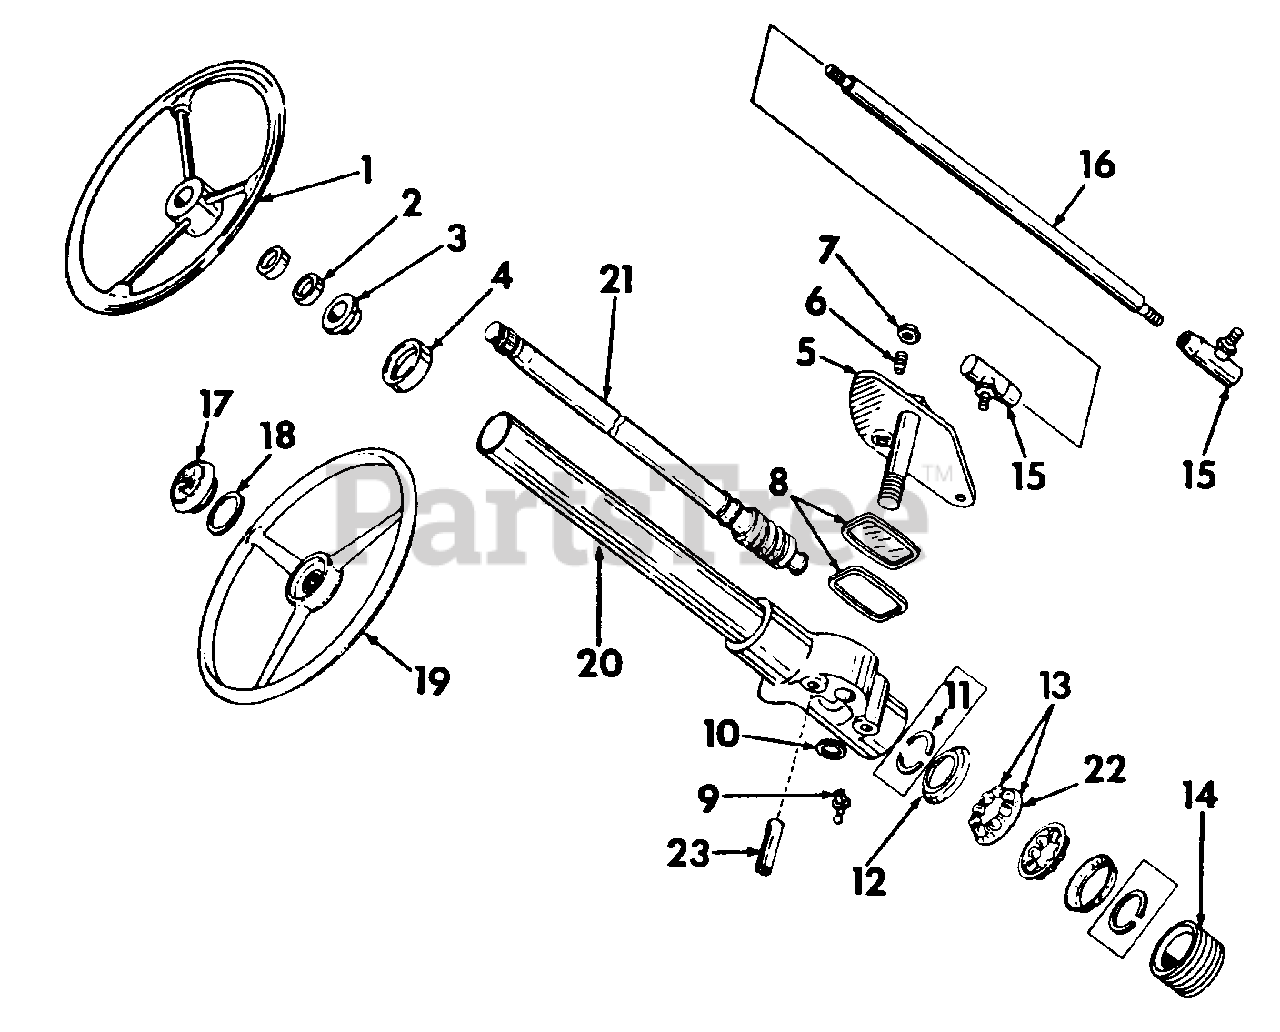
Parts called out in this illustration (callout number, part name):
2	Seal, Steering Gear
3	Bearing, Column Upper
4	Retainer, Bearing
5	Lever & Bolt Assy
6	Stud, Cam Follower
7	Nut, Cam Follower Stud
8	Package, Seal & Seal Retainer
9	Fitting, 1/4 65 Deg Angle Drive Lube
10	Washer, Flat, Bronze
12	Retainer, Bearing Ball
13	Retainer & Ball Assy
14	Plug, Adjusting
15	Joint, Tie Rod End
16	Link, Steering Gear Drag
17	Cap, Steering Wheel
18	Retainer, Steering Wheel Cap
19	Wheel, Steering
20	Tube Assy, Housing & Jacket
21	Cam & Tube Assy
22	Retainer, Ball
23	Spacer Pipe
